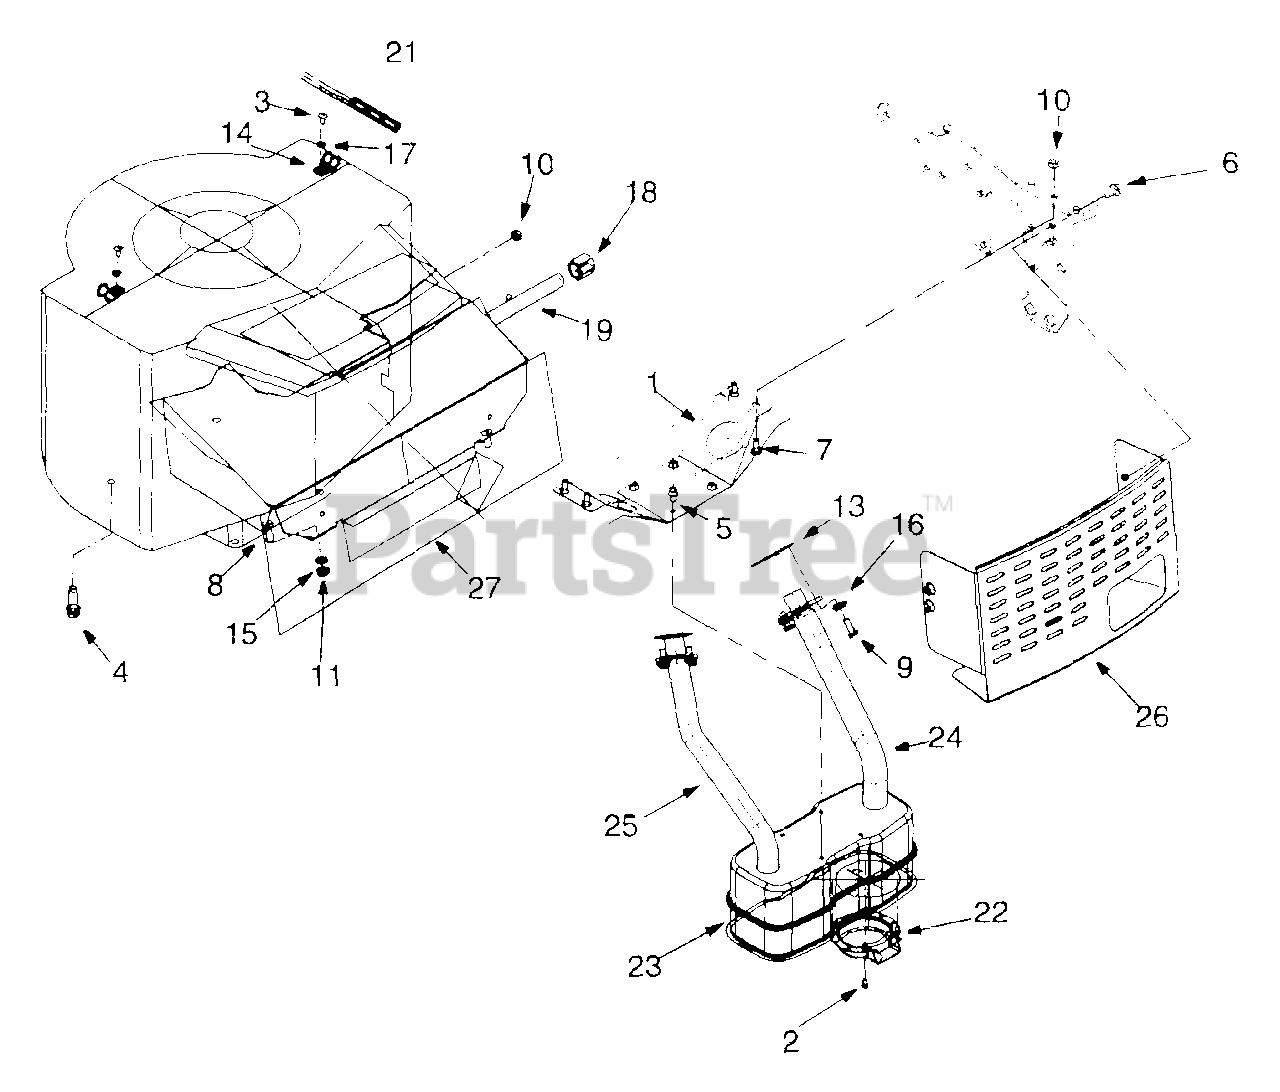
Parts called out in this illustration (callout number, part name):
1	Muffler Mounting Brkt.
2	Hex Wash Hd. Scr. #8-32 x .375" Lg.
3	Pan Hd. Scr. #10-16 x .5" Lg.
4	Hex Wash. Hd. Scr. 3/8-16 x 1.25"
5	Hex Wash. Hd. Scr. 1/4-20 x .5" Lg.
6	Hex Wash. Hd. Scr. 5/16-18 x .625"
7	Hex Bolt 1/4-20 x .62" Lg.
8	Hex Bolt 5/16-18 x .75" Lg.
9	Hex Bolt 1/4-20 x .75" Lg.
10	Hex Sems Nut 1/4-20 Thd.
11	Hex Nut 5/16-18 Thd.
13	Exhaust Gasket
14	Clamp
15	L-Wash. 5/16" I.D.
16	L-Wash. 1/4" I.D.
17	Fl-Wash. .188" I.D. x .437"
18	Oil Drain Cap
19	Straight Pipe 3/8-18 NPT. x 5" Lg.
21	Fuel Line 46" Lg.
22	Muffler Deflector
23	Muffler
24	Exhaust Pipe - L.H.
25	Exhaust Pipe - R.H.
